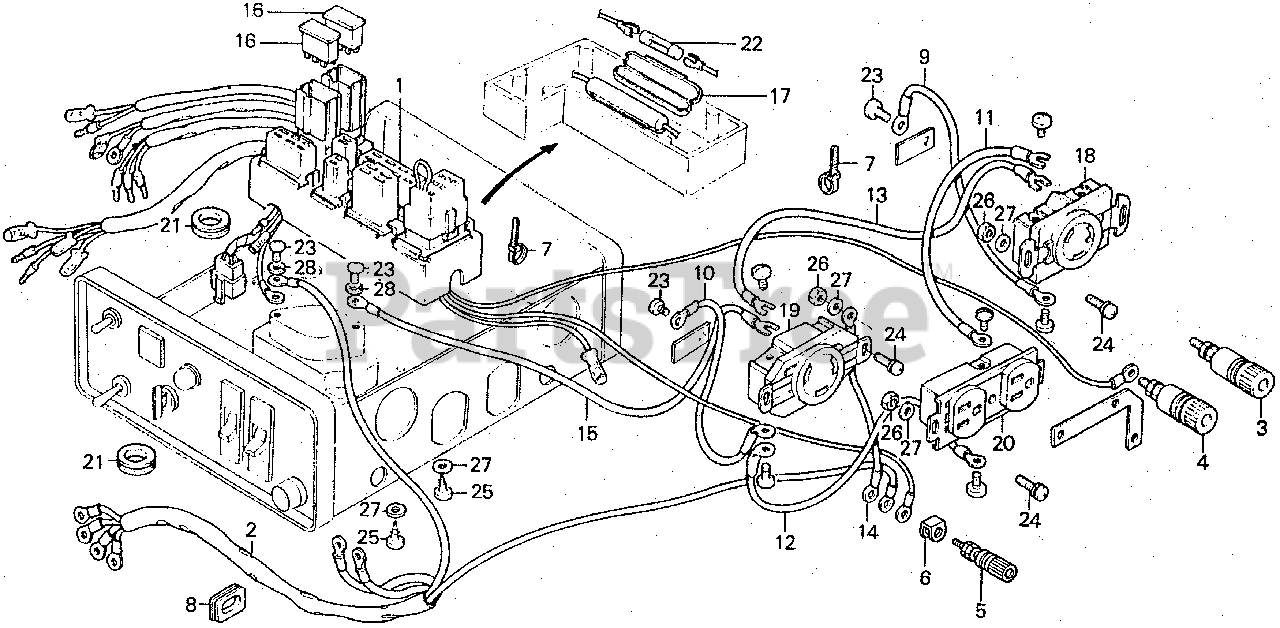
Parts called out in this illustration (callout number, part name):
1	WIRE HARNESS (NOT AVAILABLE)
1	WIRE HARNESS
2	WIRE, A.C. OUTLET
3	TERMINAL, D.C. OUT (+)
4	TERMINAL, D.C. OUT (-)
5	TERMINAL ASSY., GROUND (NOT AVAILABLE)
6	PLATE, GROUND
7	CLAMP, WIRE HARNESS
8	GROMMET, A.C. WIRE
9	WIRE, RECEPTACLE CIRCUIT BREAKER CONNECTING (200V)
10	WIRE, RECEPTACLE CIRCUIT BREAKER CONNECTING (100V)
11	WIRE, RECEPTACLE CONNECTING (100V-200V)
12	WIRE, RECEPTACLE CONNECTING
13	WIRE, RECEPTACLE CONNECTING (100V-200V)
14	WIRE, GROUND
15	WIRE, IDLE CONTROL UNIT CONNECTING (NOT AVAILABLE)
16	STACK ASSY., DIODE (2.7A)
17	CASE, FUSE CONNECTOR
18	RECEPTACLE (20A 250V) (NOT AVAILABLE)
19	RECEPTACLE (3-PRONG) (30A/125V)
20	RECEPTACLE (15A-125V)
21	GROMMET, WIRE HARNESS
23	SCREW, PAN (5X8)
24	SCREW-WASHER (4X12)
25	SCREW, TAPPING (4X12)
26	NUT, HEX. (4MM)
27	WASHER, PLAIN (4MM)
28	WASHER, SPRING (5MM)
